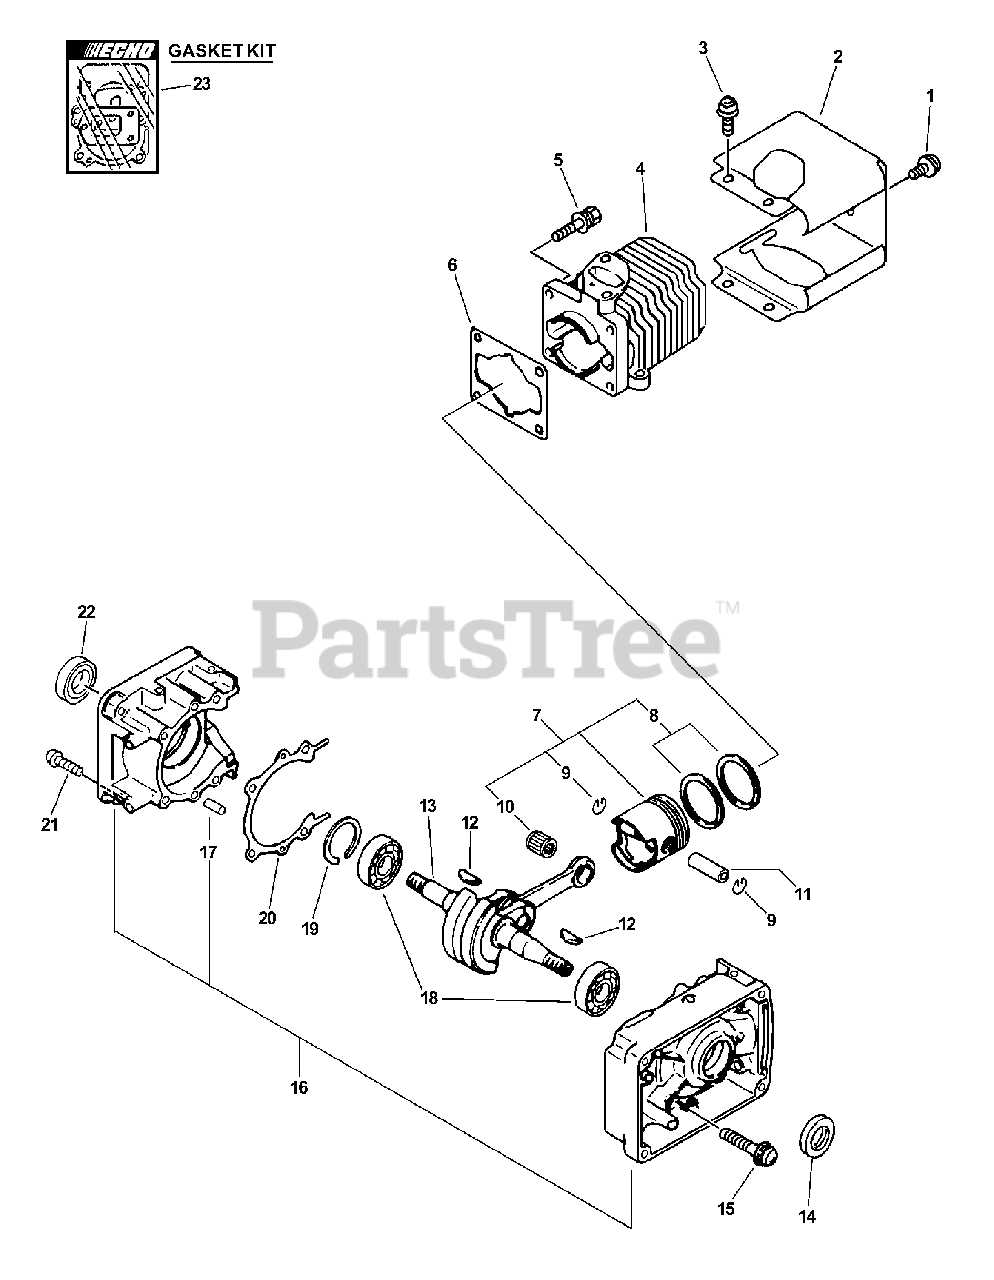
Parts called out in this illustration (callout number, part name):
1	SCREW - 5X10
2	SHIELD, CYLINDER
3	SCREW - 4X10
4	CYLINDER
5	SCREW - 5X20
6	GASKET, CYLINDER
7	PISTON KIT
8	RING, PISTON
9	RING, RETAINING
10	BEARING, NEEDLE
11	PIN, PISTON
12	KEY - 3X14
13	CRANKSHAFT ASSY
14	SEAL, OIL
15	SCREW - 5X30
16	CRANKCASE KIT
17	PIN - LOCATING
18	BEARING, BALL - 6201
19	RING, RETAINING - 32
20	GASKET, CRANKCASE
21	SCREW - 5X20
22	SEAL, OIL
23	GASKET KIT
